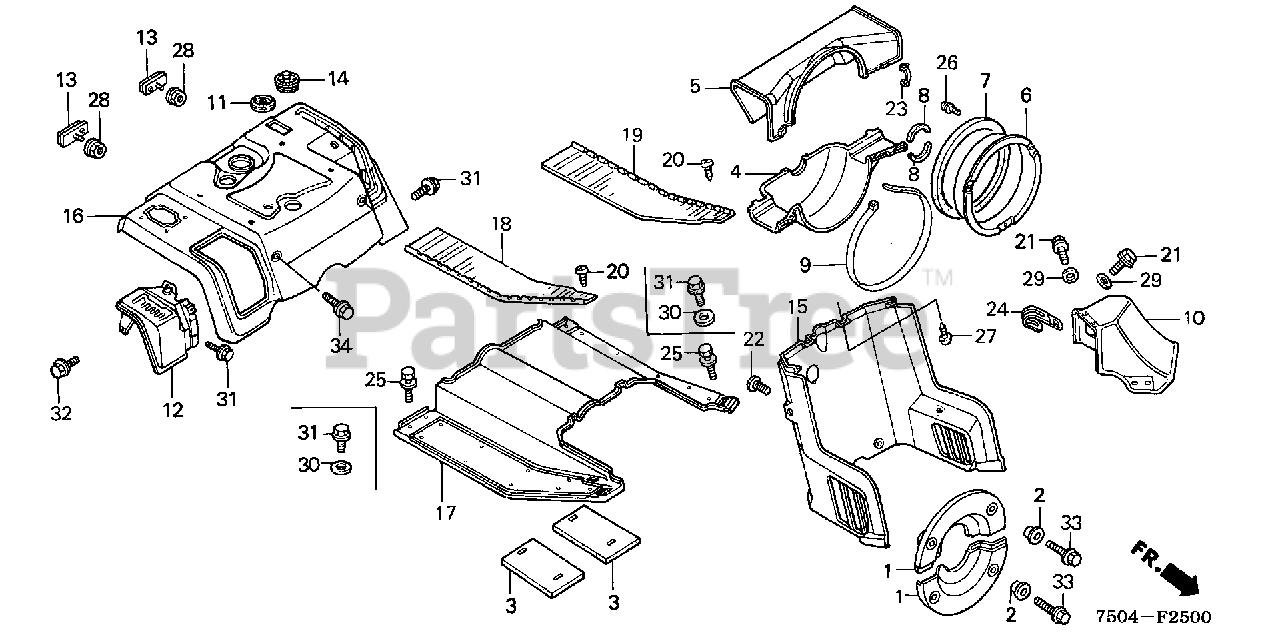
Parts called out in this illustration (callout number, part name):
4	DUCT (LOWER)
5	DUCT (UPPER)
6	GUIDE, ENGINE DUCT
7	SEAL, ENGINE DUCT
8	SEAL, PROPELLER DUCT
9	BAND (650MM)
10	GUIDE, AIR
11	GROMMET, WIRE
12	GUIDE, CHANGE LEVER *R136* (DIANA RED)
13	REFLECTOR, REFLEX
15	SHELL, COMPARTMENT *NH105* (MAT BLACK)
16	FENDER, RR. *R136* (DIANA RED)
17	FLOOR *R136* (DIANA RED)
18	FLOOR MAT, R.
19	FLOOR MAT, L.
20	SCREW, TAPPING (4X14)
21	BOLT, FLANGE (6X12)
22	SCREW, METER VISOR SETTING
23	CLIP, ENGINE DUCT
24	CLIP (2X60)
25	BOLT-WASHER (6X12)
26	SCREW-WASHER (6X12)
27	SCREW, TAPPING (6X16)
28	NUT, FLANGE (5MM)
30	WASHER, PLAIN (6MM)
31	BOLT, FLANGE (6X12)
32	BOLT, FLANGE (6X12)
34	BOLT, FLANGE (8X16)
